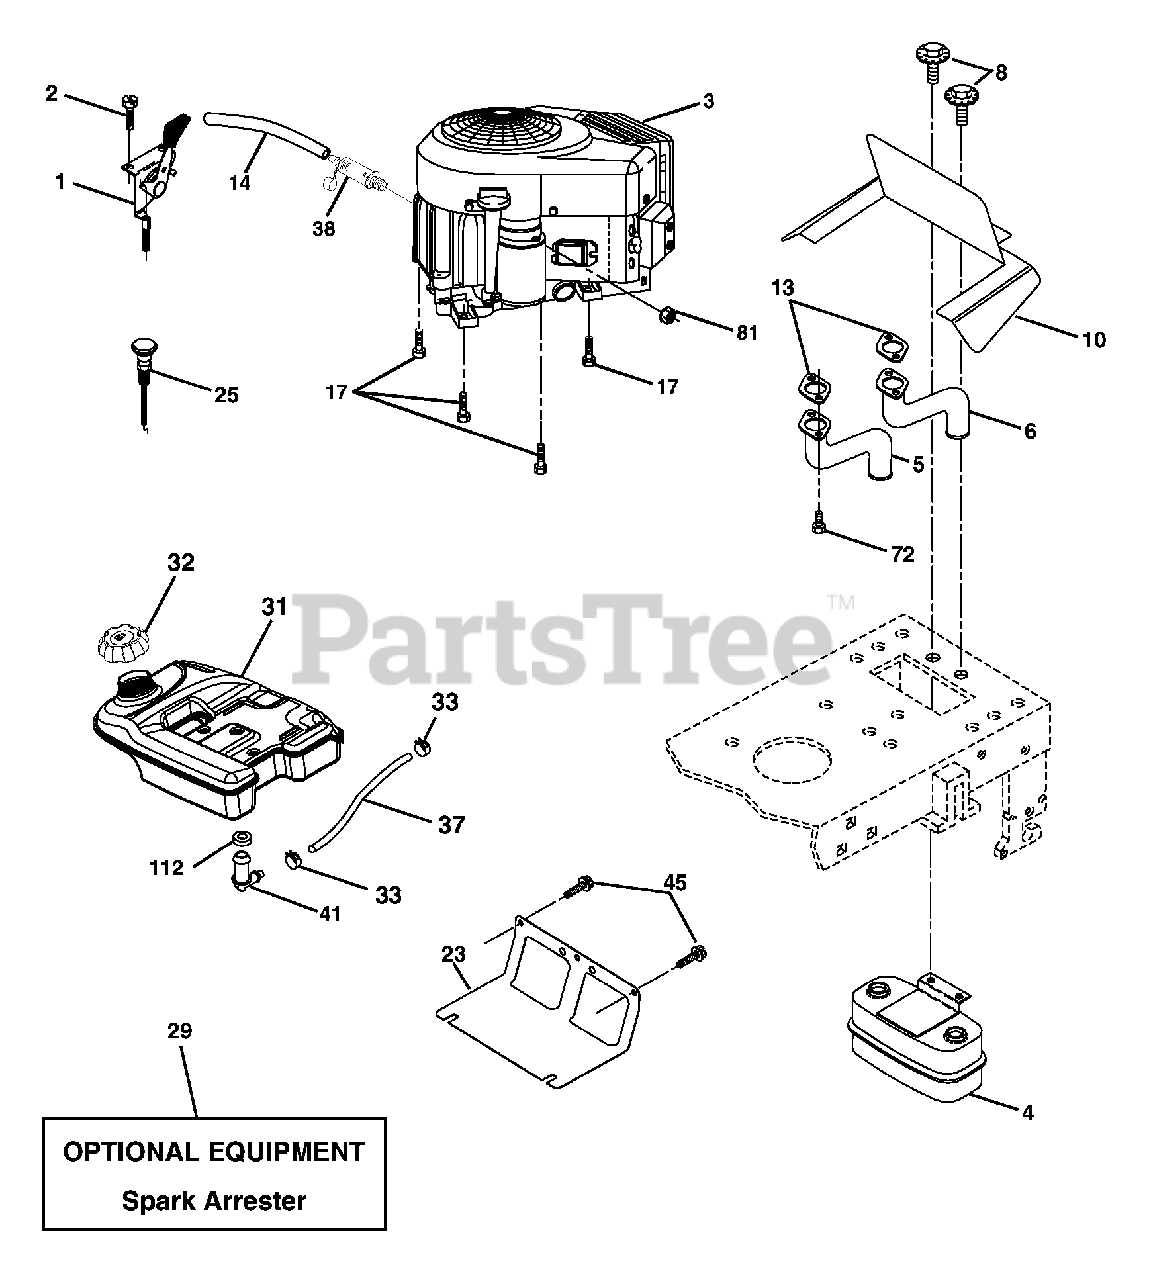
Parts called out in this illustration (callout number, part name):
1	Control Throttle
2	Screw 10 x 3/4 Single Lead-Hex
4	Muffler Asm Twin Lo-Tone
5	Pipe Exhaust LH
6	Pipe Exhaust RH
8	Bolt 5/16-18 unc x 3/4 w/Sems
10	Shield
13	Muffler Gasket
14	Tube Drain Oil Easy
17	Screw Thdrol 3/8-16 x 1-1/2
23	Shield Heat
25	Choke Control
29	Kit Spark Arrestor (Flat Scrn)
31	Tank Fuel 4.0 Rear
32	Cap Asm Fuel
33	Clamp Hose Black
37	Line Fuel
38	Plug Drain Oil
41	Stem Tank Fuel
45	Screw Hexwsh Thdr 3/8-16 x 3/4
72	Screw 5/16-18 x 1
112	Bushing
